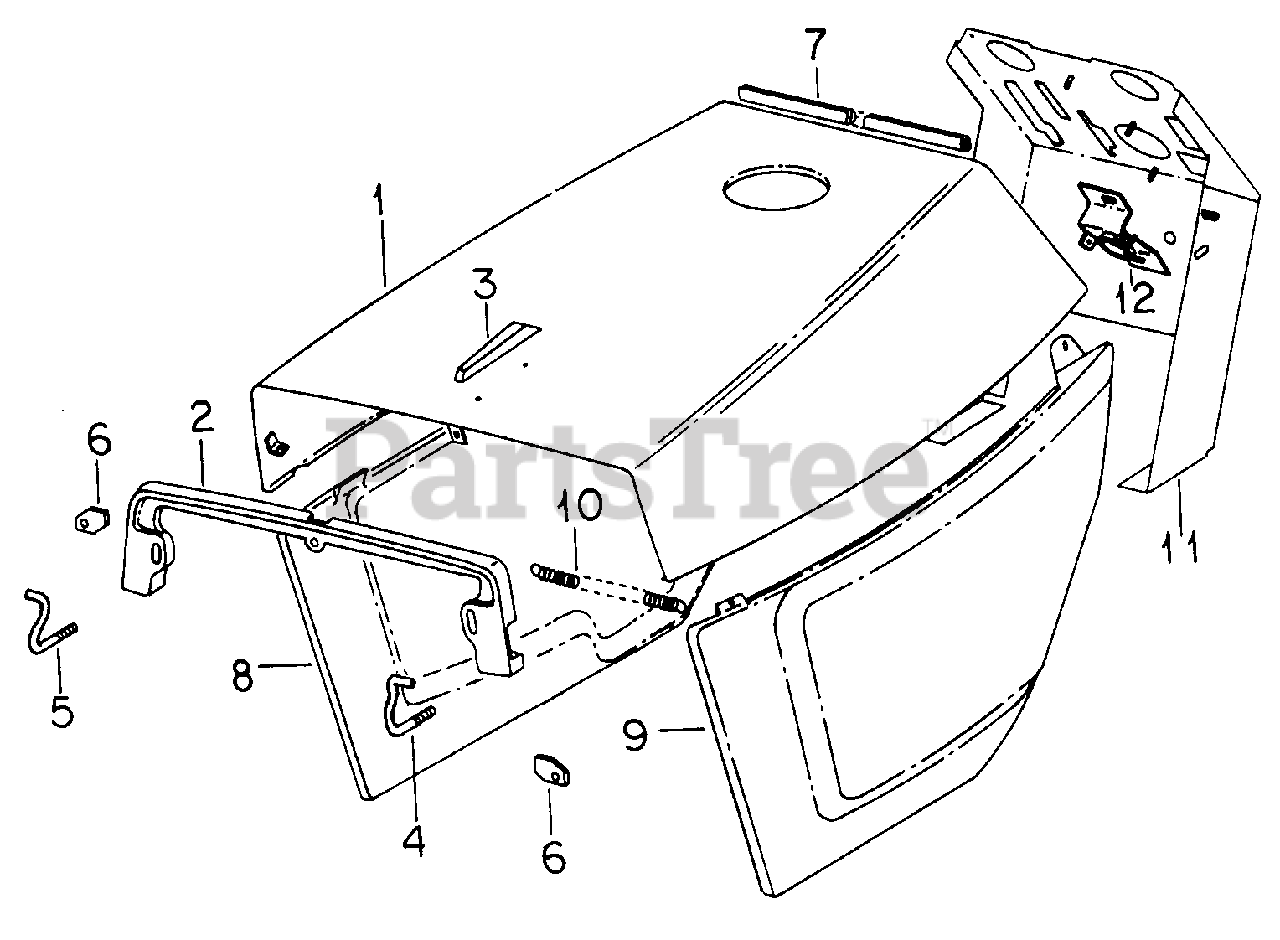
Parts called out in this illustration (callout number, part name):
1	Hood Assy
2	Support, Hood
3	Ornament, Hood
4	Hinge, LH Hood
5	Hinge, RH Hood
6	Plate, Hood Hinge
7	Seal, Edge
10	Spring, Side Panel
11	Pedestal Assy
12	Support Assy, Steering Column
